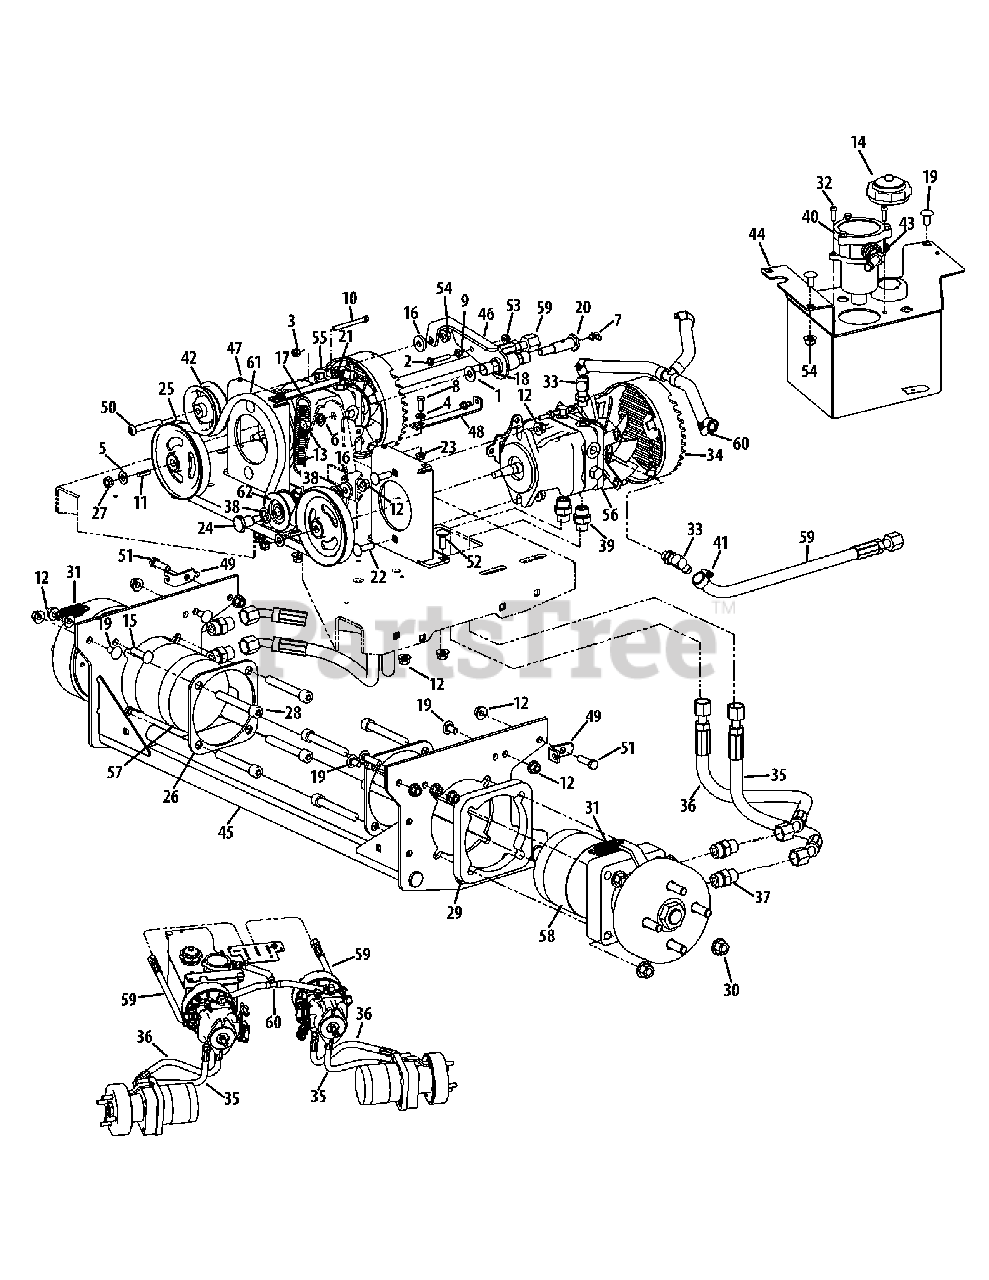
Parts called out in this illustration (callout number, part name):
1	Washer, .438 x 1.00 x .078
2	Hex Screw, 1/4-20 x 1.50
3	Nut, 1/4-20
4	Washer, .281 x .625 x .063
5	Washer, .406 x .813 x .063
6	Lock Washer, .438 x .762 x .113
7	Grease Fitting, 1/4-28 x .788
8	Hex Screw, 1/4-20 x .750
9	Nut, 1/4-20
10	Screw, 1/4-20 x .500
11	Key, .188 x .188 x .875
12	Flange Counter Lock Nut, 3/8-16
13	Nut, 7/16-14
14	Hydro Oil Tank Cap
15	Carriage Bolt, 3/8-16 x 1.50
16	Washer, .390 x 1.00 x .180
17	Extension Spring, 1.00 x 5.00 x .125
18	Sleeve Bearing, .628 x.753 x.625
19	Carriage Bolt, 3/8-16 x .75
20	Shoulder Bolt, 7/16-14 x .60 x 1.6
21	Hex Flange Screw, 1/4-20 x .500
22	Carriage Bolt, 3/8-16 x 1.25
23	Flange Top Lock Nut, 1/4-20
24	Shoulder Bolt, 3/8-16 x .625 x .830
25	Hydro Pump Pulley
26	Hydro Motor Back-Up Plate
27	Counter Lock Nut, 3/8-24
28	Socket Cap Screw, 1/2-13 x 3.50
29	Hydro Wheel Motor Spacer
30	Flange Top Lock Nut, 1/2-13
31	Extension Spring, .74 x 2.7 x .075
32	Socket Cap Screw, 1/4-20 x .750
33	Elbow Fitting, 9/16 x 1/2
34	Pump Fan Shroud
35	Pump Motor Hose Assembly, 16.38
36	Pump Motor Hose Assembly, 18.75
37	Hydro Adapter, 8 x 10
38	Washer, .625 x 1.00 x .048
39	Hydro Adapter, 8 x 8
40	Hydro Filter
41	Hose Clamp
43	45° Fitting, 3/4 x 1/2
44	Hydro Tank Assembly
45	Wide Motor Frame
47	Pump Assembly Mount Bracket
48	Pump Mount Brace
49	Brake Cable Bracket
50	Screw, 3/8-16 x 2.25
51	Hex Screw, 3/8-16 x 1.25
52	Carriage Bolt, 3/8-16 x 1.00
53	Flange Lock Nut, 1/4-20
54	Flange Lock Nut, 3/8-16
55	LY Hydro Pump
56	RH Hydro Pump
57	LH Hydro Motor w/ Brake
58	RH Hydor Motor w/ Brake
59	Wheel Pump to Manifold Hose Assy.
60	Return Tee Hydro Hose
62	Idler Pulley
